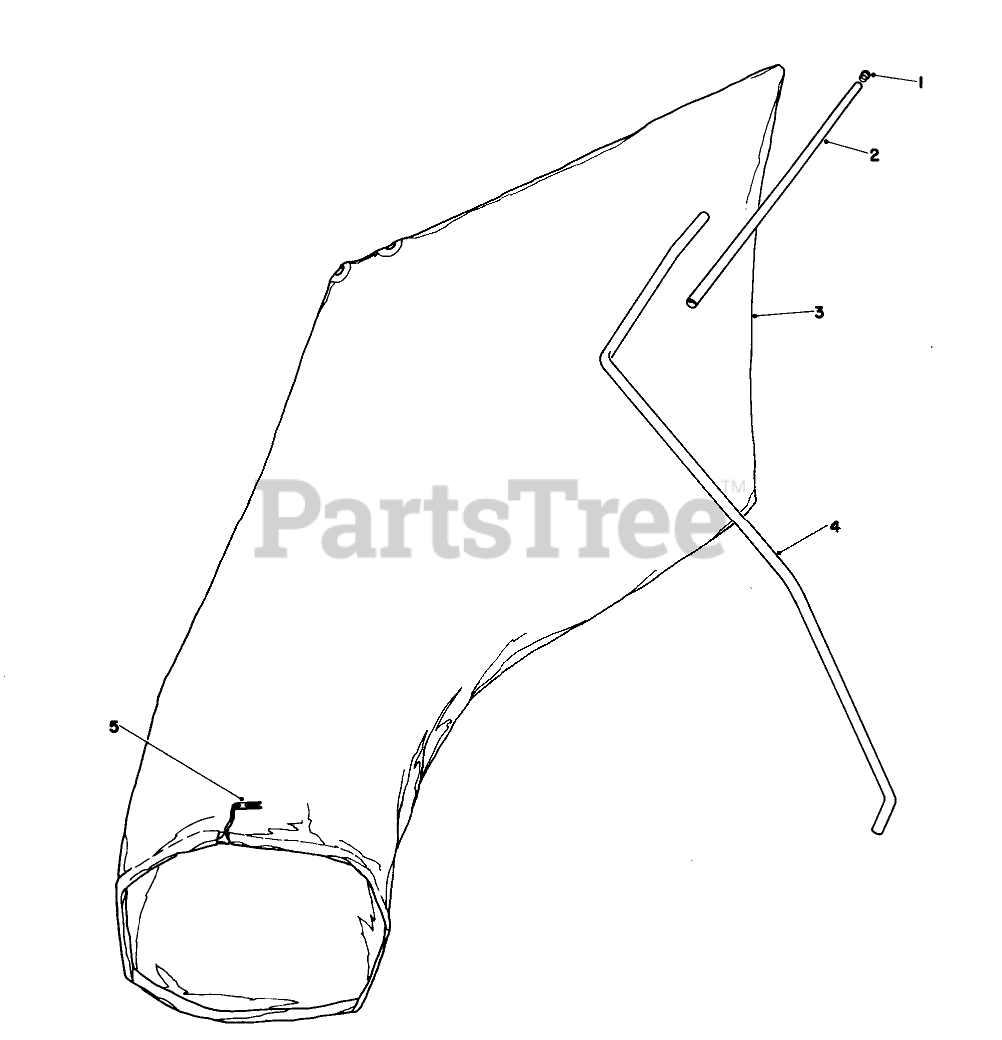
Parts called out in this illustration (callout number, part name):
2	BAG HANGER TUBE
3	GIANT BAG(29-9860) WW
4	HANGER ROD
5	BAG CORD FASTENER
